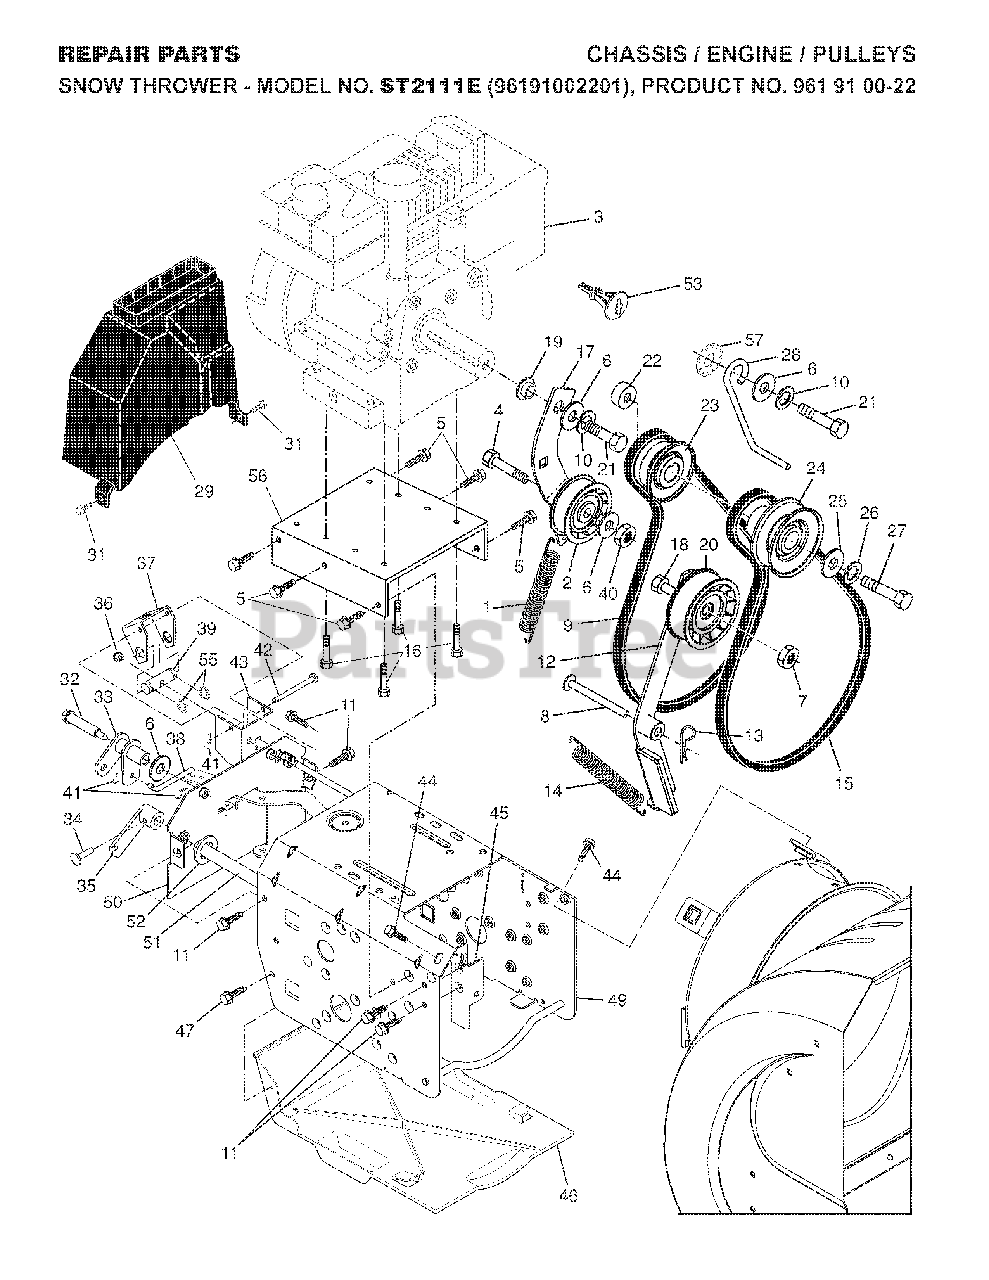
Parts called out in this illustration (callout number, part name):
1	RP SPRING, TRACTION IDLER
2	PULLEY.W/SPACER.2.25
4	BOLT.5/16-18X1-1/4 FULL.THREAD
5	SELF-TAPPING SCREW 5/16-18X3/4
6	STEEL WASHER
7	LOCKNUT 5/16-18
8	PIN, IDLER PIVOT
10	LOCKWASHER
11	SCREW, HEX HEAD 5/16-18 X 1/2
12	ARM PAD ASSY
13	RETAINER CLIP PM
14	SPRING, BRAKE
15	BELT-V.IMPELLER.HS
16	BOLT 3/8-16X1-1/8
17	IDLER ARM
18	HEX BOLT
19	BUSHING, IDLER PIVOT
20	PULLEY.W/SPACER.2.75
22	SPACER.ENGINE.PULLEY
23	PULLEY, ENGINE TRACTION DRIVE
24	PULLEY
25	WASHER, FLAT 3/8
26	LOCKWASHER
27	SCREW, HEX HD 3/8-24 X 1-3/8
28	GUIDE BELT
29	COVER.BELT.HS
31	SCREW
32	BOLT, SHOULDER 5/16-18
33	BELLCRANK SHIFTER
34	CLEVIS PIN
35	ARM, AUGER CONTROL
36	NUT.71038.31-18.HEX.NYLOCK
37	BRACKET, PIVOT
38	LINK, SPEED CONTROL
39	TRUNNION, TRACTION
40	NUT.CENTERLOCK.5/16-
41	RETAINER CLIP
42	PIN, PIVOT BRACKET
44	SCREW 3/8-16X1
45	BRACKET, IDLER PIVOT
46	PAN, FRAME BOTTOM
47	SCREW, HEX HEAD, TAPPING
48	NUT, SPEED 5/16-18
51	SHAFT, AUGER CONTROL
52	THRUST WASHER
53	KEY.PUSH/PULL.B&S.
55	RETAINING RING LT
57	WASHER EXT TOOTH LOCK 5/16
